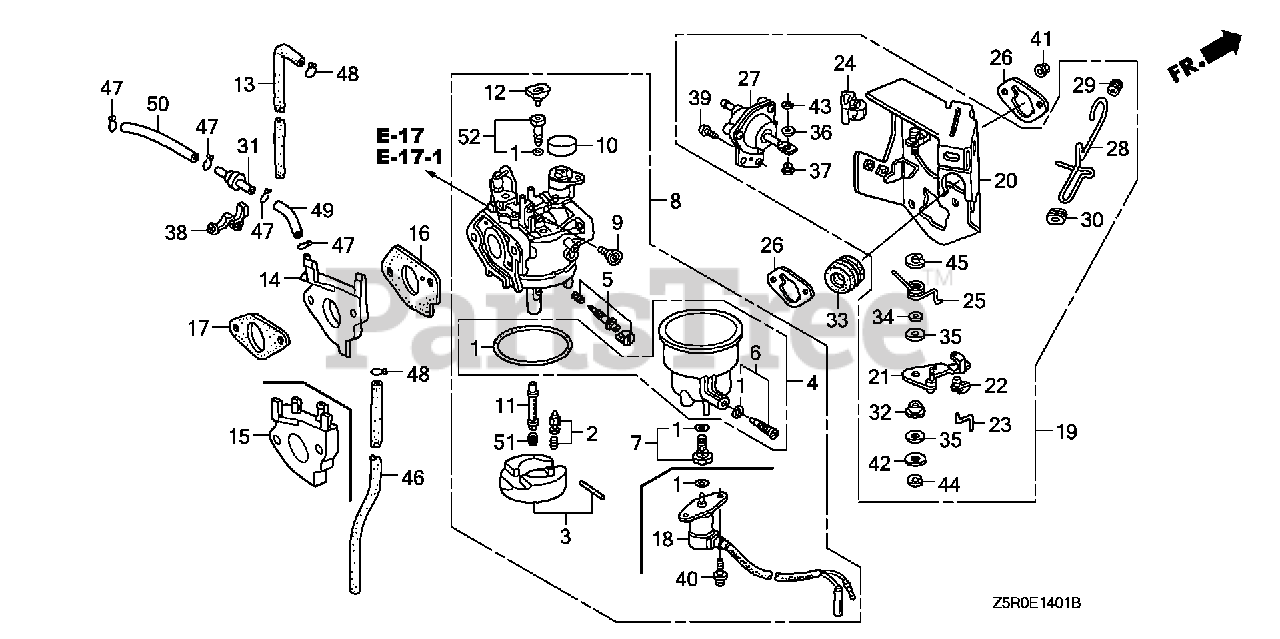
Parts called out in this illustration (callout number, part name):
1	GASKET SET
2	VALVE SET, FLOAT
4	CHAMBER SET, FLOAT
6	SCREW SET, DRAIN (CARBURETOR NO.)
8	CARBURETOR ASSY. (BE89B A)
9	SCREW, THROTTLE STOP
10	CAP, CHOKE DUST
11	NOZZLE, MAIN
12	COLLAR, SETTING
14	INSULATOR, CARBURETOR
16	GASKET, CARBURETOR
17	GASKET, INSULATOR
18	VALVE ASSY., SOLENOID
19	STAY ASSY., MANUAL CHOKE
20	STAY, SOLENOID
21	LEVER, CHOKE
22	JOINT, ROD
23	ROD, CHOKE
24	STOPPER, CHOKE ROD
25	SPRING, MANUAL CHOKE
26	GASKET, AIR CLEANER
27	DIAPHRAGM ASSY.
28	ROD, CHOKE CONTROL
29	GROMMET, CHOKE ROD
30	GUIDE, CHOKE ROD
31	VALVE, DASHPOT CHECK
32	BUSH, ARM PIVOT
33	GROMMET, FENDER
34	WASHER, CHOKE LEVER
35	SEAL, CHOKE LEVER
36	WASHER, THRUST (2.7X8)
37	COLLAR, LEVER
38	CLIP, WIRE HARNESS
39	SCREW, PAN (5X12)
40	SCREW-WASHER (5X12)
41	NUT, FLANGE (6MM)
42	WASHER, PLAIN (5MM)
43	E-RING (2MM)
44	E-RING (4MM)
45	E-RING (7MM)
47	CLIP, TUBE (B7)
49	BULK HOSE, VACUUM (3.5X8000) (3.5X75)
50	BULK HOSE, VACUUM (3.5X8000) (3.5X130)
51	JET, MAIN (#98)
51	JET, MAIN (#100)
51	JET, MAIN (#102)
51	JET, MAIN (#105)
52	JET SET, PILOT (#45)
